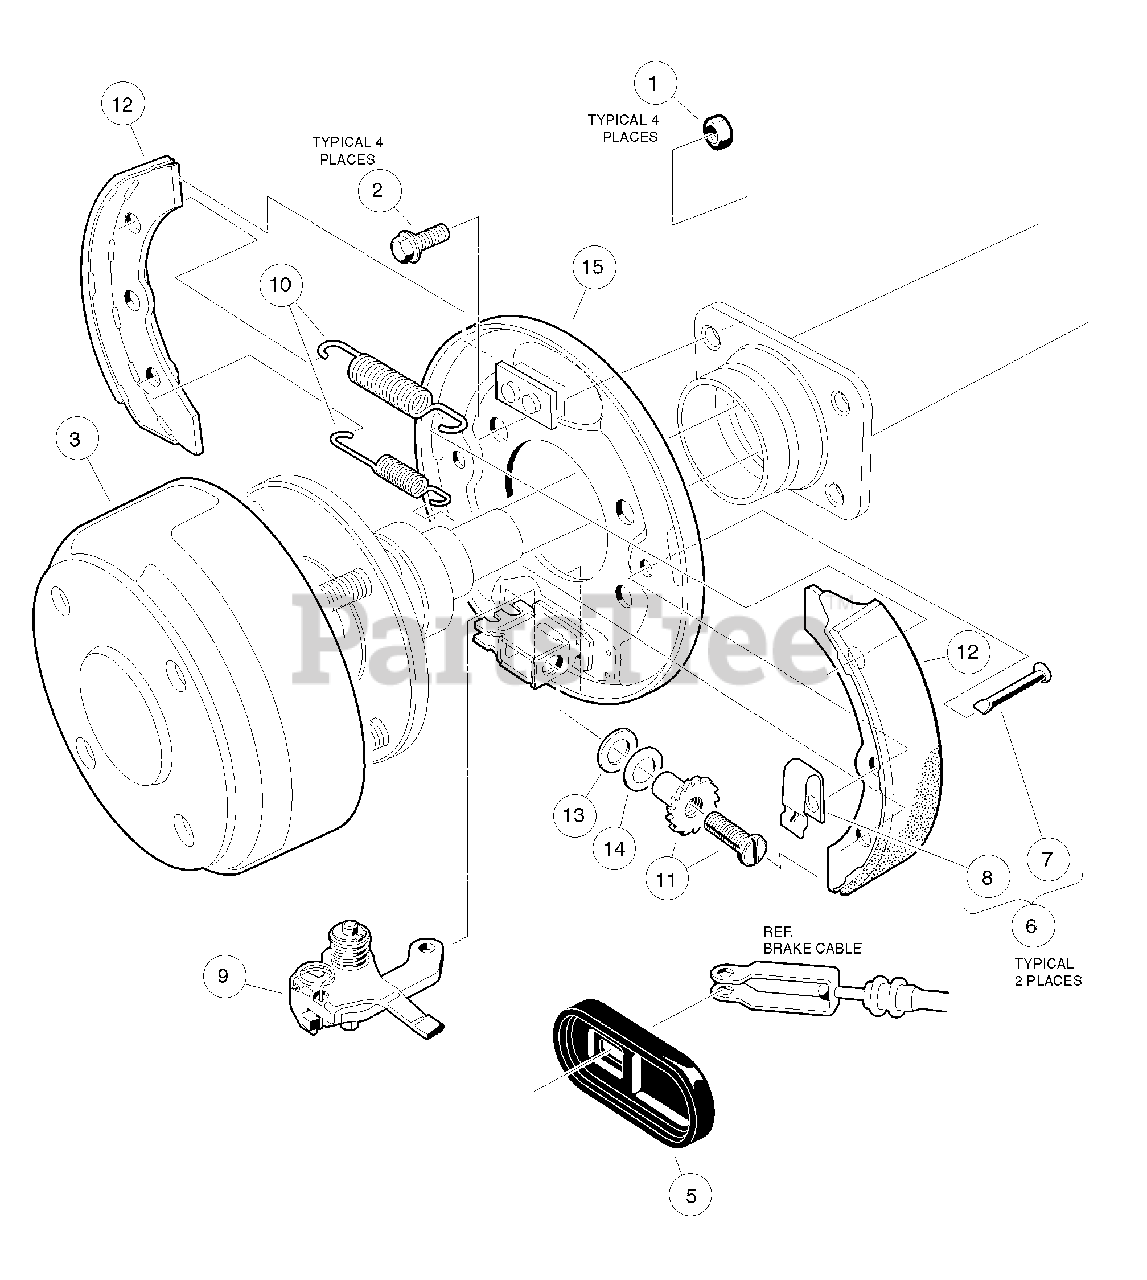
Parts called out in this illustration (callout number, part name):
1	Nut, 5/16-24 Hex Head Cone
2	Bolt, Brake Cluster Mounting
3	Drum without Center Hole, Brake
4	Cluster Assembly, Right
5	Dust Cover
6	Kit, Shoe Retainer
7	Pin
8	Shoe Clamp Spring
9	Lever Assembly, Self-Adjusting Brake, Right
10	Package, Brake Spring, Self-Adjusting
11	Adj Mechanism, S.A. Brakes, Right
12	Package, Brake Shoe, Self-Adjusting
13	Plate, Washer, Brake, Self-Adjusting
14	Washer, Brake, Self-Adjusting
15	Plate Assembly, Right Brake Backing
16	Cluster Assembly, Left Brake
17	Dust Cover
18	Kit, Shoe Retainer
19	Pin
20	Shoe Clamp Spring
21	Lever Assembly, Self-Adjusting Brake, Left
22	Package, Brake Spring, Self-Adjusting
23	Adjusting Mechanism, Self-Adjusting Brake, Left
24	Package, Brake Shoe, Self-Adjusting
25	Plate, Washer, Brake, Self-Adjusting
26	Washer, Brake, Self-Adjusting
27	Plate Assembly, Left Brake Backing
